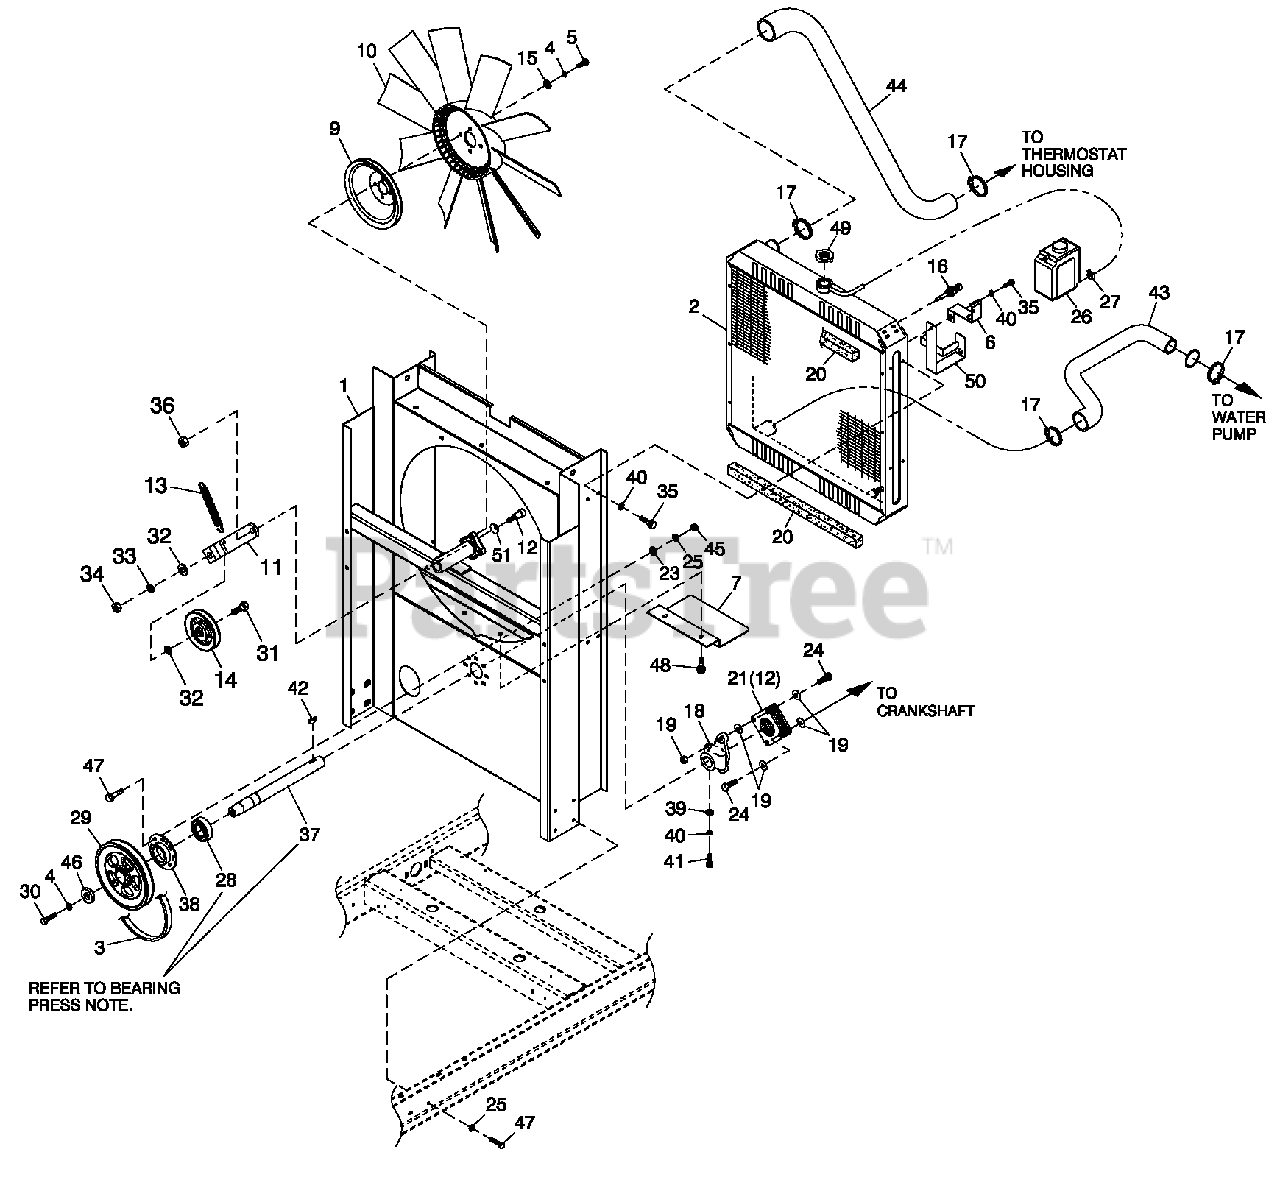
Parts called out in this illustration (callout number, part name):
1	WELDMENT RADIATOR SUPPORT 2.4L
2	RADIATOR 598 X 568 X 49 CPL RH
3	V- BELT 31/64" X 57-3/8"
4	WASHER LOCK M10
5	SCREW HHC M10-1.5X30G10.9
6	BRACKET, SIGNAL CONDITIONER (USED ONLY WITH QTA PRODUCT)
7	SHIELD RADIATOR C4
9	PULLEY FAN V-GROOVE 9"
10	FAN COOL 22" DIA 10 BLADE LH
11	ARM TENSIONER
12	SHOULDER BOLT 3/8 X 1/2"
13	SPRING TENSION CPL
14	PULLEY V- BELT 4" FLANGED
15	WASHER FLAT 3/8-M10 ZINC
16	PRO BE COOLANT LEVEL 3/8 NPTF
17	CLAMP HOSE #28 1.32-2.25
18	HU B FLEX PLATE
19	WASHER FLEX (THIN)
20	TAPE FOAM 1 X 1 (26.75" LG)
21	DISK FLEX
23	WASHER FLAT 1/4-M6 ZINC
24	SCREW HHC 5/16-24X1.124
25	WASHER LOCK M6-1/4
26	TANK COOLANT RECOVERY
27	CLAMP HOSE BAND 1/4
28	BEARING #6205 2NSE C3 E SRI2 S
29	PULLEY 4.5" DIA MACHINED
30	SCREW HHCM10-1.5X30 G8.8
31	SCREW HHC 1/2-13 X 2" G8
32	WASHER FLAT 1/2 ZINC
33	WASHER LOCK 1/2
34	NUT HEX 1/2-13 STEEL
35	SCREW HHFC M8-1.25 X 20 W/M6
36	NUT HEX LOCK 5/16-18 NY INS SS
37	SHAFT FAN DRIVE
38	RETAINER BEARING
39	WASHER FLAT 5/16-M8 ZINC
40	WASHER LOCK M8-5/16
41	SCREW HHC M8-1.25X 35 G8.8
42	KEY WOODRUFF 4X 1 9D
43	HOSE LOWER RADIATOR G2
44	HOSE UPPER RADIATOR G2
45	NUT HEX M6X 1.0 G8YEL CHR
46	SPACER .5 X 1.5 X .25 STL/ZINC
47	SCREW HHFC M6-1.0X 20 G8.8
48	SCREW THF M6-1 X 16 N WA Z/JS
49	CAP RADIATOR 13 PSI
50	BRACKET COOLANT TANK
51	WASHER BELLEVILLE .75X.38X.028
